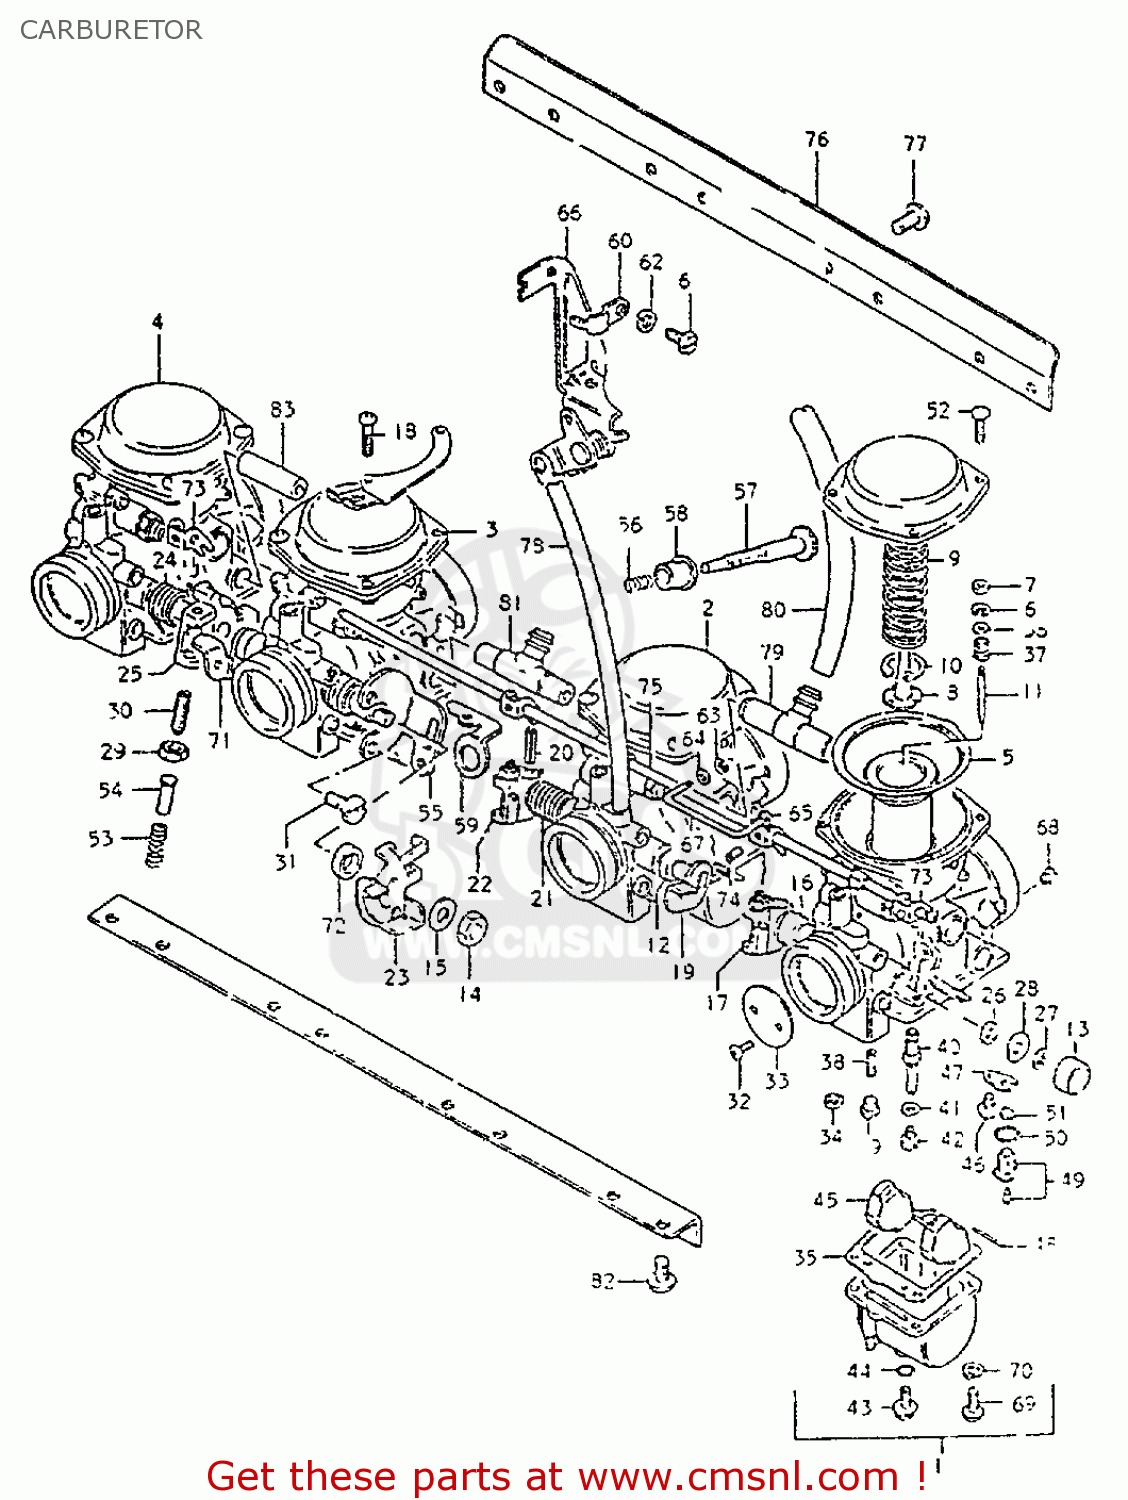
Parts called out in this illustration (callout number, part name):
1	CARBURETOR, NO.1
2	CARBURETOR, NO.2
3	CARBURETOR, NO.3
4	CARBURETOR, NO.4
5	DIAPHRAGM ASSEMBLY
6	CLIP,NEEDLE
7	RING
8	HOLDER,GUIDE
9	SPRING
10	E RING
11	NEEDLE, JET (5F42-3)
12	GASKET,THROTTLE SHAFT (NAS)
13	CAP
14	NUT
15	WASHER
16	SPRING,THROTTLE SHAFT
17	SHAFT,THROTTLE
18	SCREW
19	SHAFT,THROTTLE
20	PIN,THROTTLE SHAFT
21	SPRING,THROTTLE SHAFT
22	LEVER,THROTTLE SHAFT
23	LEVER ASSEMBLY,THROTTLE
24	SPRING,THROTTLE SHAFT
25	SHAFT,THROTTLE
26	SEAL
27	E RING
28	GASKET,THROTTLE SHAFT (NAS)
29	NUT
30	SCREW
31	SCREW,THROTTLE ADJUST B
32	SCREW
33	VALVE,THROTTLE (BUTTERFLY)
34	GASKET (NAS)
35	GASKET,FLOAT CHAMBER (NAS)
36	WASHER
37	SPRING
38	JET
39	PLUG,NEEDLE JET
40	JET, NEEDLE (X-6)
41	WASHER,NEEDLE NOZZLE
42	JET
43	PLUG,DRAIN
44	GASKET (NAS)
45	FLOAT
46	SCREW
47	PLATE
48	PIN,FLOAT
49	VALVE ASSEMBLY,NEEDLE
50	O-RING,NEEDLE VALVE
51	FILTER
52	SCREW
53	SPRING,THROTTLE SCREW
54	PIN,THROTTLE LEVER
55	BRACKET,THROTTLE ADJUST
56	SPRING
57	SCREW
58	BUSH
59	BRACKET,THROTTLE ADJUST
60	BRACKET,STARTER
61	BOLT
62	LOCK WASHER
63	CAP,LEVER
64	SEAT,SPRING
65	LEVER ASSY
66	BRACKET
67	ROD,STARTER LEVER
68	JET,AIR
69	SCREW
70	LOCK WASHER
71	SHAFT,THROTTLE
72	WASHER
73	LEVER
74	SCREW
75	SHAFT,STARTER
76	BRACKET
77	SCREW
78	HOSE
79	NIPPLE
80	HOSE
81	NIPPLE,CARBURETOR
82	SCREW 6X12
83	NIPPLE
